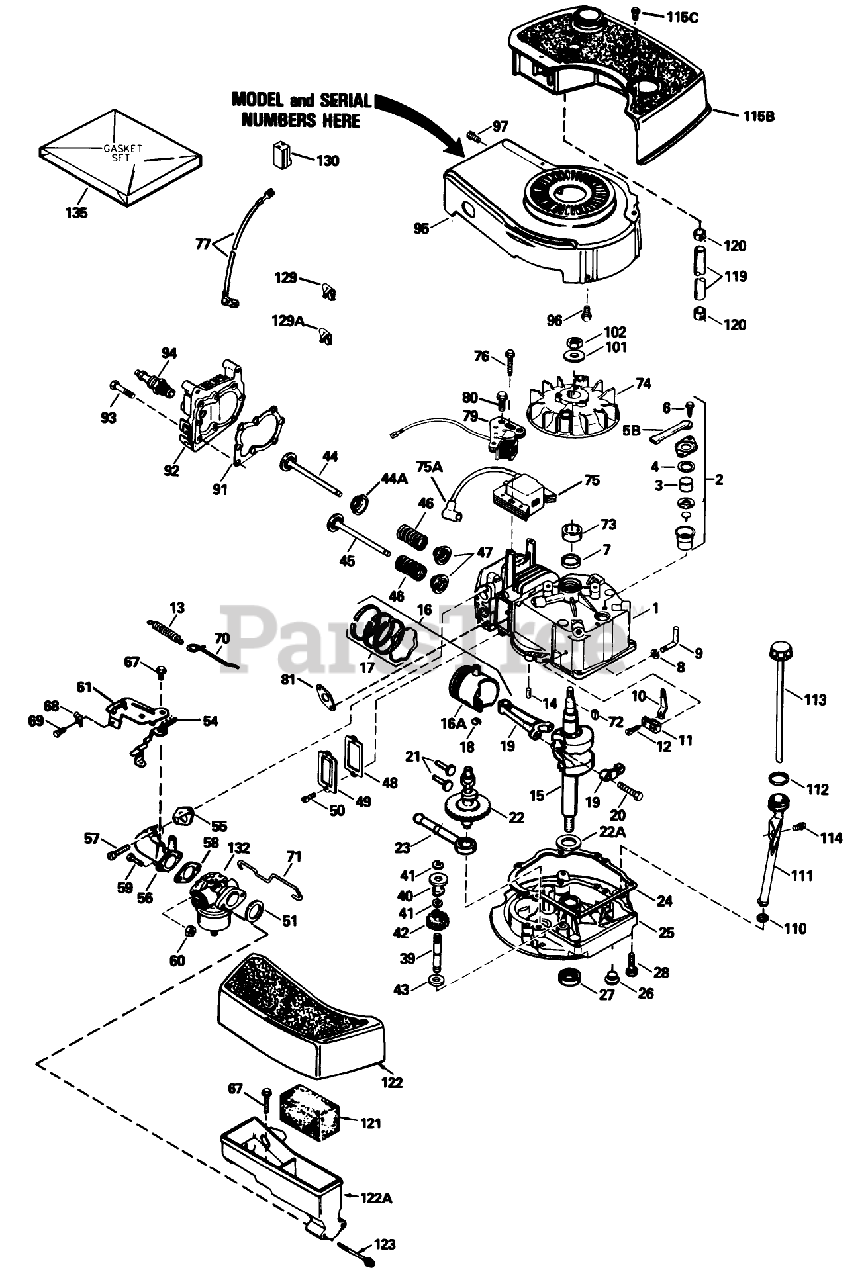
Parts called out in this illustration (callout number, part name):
1	Cylinder Assy. (Inc. #2 4)
2	Breather Assy. (Incl. Ref. #46 thru 51)
3	Element-Breather
4	Gasket-Breather
5B	Tube, Breaker
6	Screw (10-24 x 9/16)
7	Seal-Oil
8	Washer-Flat
9	Rod, Governor (Incl. No. 36)
10	Governor Lever
11	Clamp-Lever, Governor
12	Screw
13	Spring Governor
14	Pin-Dowel
15	Crankshaft
16	Piston-Pin Ring Assy. (Std.)(Incl. Ref. #16A, 17 18)
16	Piston-Pin Ring Assembly (.010 oversize)(Incl. Ref. #16A, 17 18)
16	Piston, Pin Ring Assy. (.020 Oversize)(Incl. Ref. #13A, 14, 15)
16A	Piston Pin Assy. (Std.)(Incl. Ref. #14)
16A	Piston Pin Assembly (.010 oversize)(Incl. Ref. #18)
16A	Piston Pin Assy. (.020 Oversize) (Incl. Ref. #14)
17	Ring Set-Piston (Std.)
17	Ring Set, Piston(.0100versize)
17	Ring Set (.020" OS)
18	Ring-Retaining, Piston Pin
19	Rod Assy., Connecting (Incl. Ref. #17)
20	Bolt-Rod, Connecting
21	Lifter-Valve
22	Camshaft(Mech.Comp. Release)
22A	Washer-Thrust
23	Oil Pump ASM
24	Gasket
25	Flange-Mounting (Incl. Ref. #26, 27 39)
26	Plug Oil Drain
27	Seal-Oil
28	Screw (1/4-20 x 1-1/4)
39	Shaft-Governor
40	Spool-Governor
41	Ring-Retaining
42	Governor Gear ASM
43	Washer
44	Valve, Intake (Std.) (Incl. Ref. #40)
44	Valve, Intake (1/32" oversize)(Incl. No. 40)
44A	Seal Assy., Intake
45	Valve, Exhaust (Std.)(Incl. No. 40)
45	Valve, Intake (1/32" oversize)(Incl. No. 40)
46	Spring-Valve
47	Cap-Valve, Spring
48	Gasket-Cover, Valve
49	Cover-Valve
50	Screw
51	Gasket-Air Cleaner
54	Lever Control
55	Gasket-Intake Pipe
56	Pipe, Intake (Incl. No. 68)
57	Screw (1/4-20 x 1)
58	Gasket-Carburetor
60	Nut and Lock Washer (1/4-28)
61	Control Assy., Speed (Incl. Nos, 76, 78 89)
67	Screw, Hex Washer Hd Shoulder Self-Tap
68	Conduit
69	Screw (10-32 x 3/8)
70	Link Governor Spring
71	Link-Throttle
72	Key-Flywheel
73	Spacer
74	Flywheel
75	Solid State
75A	Cover-Spark Plug
76	Screw
77	Wire-Ground
79	Coil, Alternator
80	Screw (8-32x27/64)
81	Gasket, Exhaust
91	Gasket-Cylinder Head
92	Head-Cylinder
93	Screw (5/16-18x1-1/2)
94	Spark Plug-Resistor (R J19 L M)
95	Housing-Blower
96	Screw (1/4-20x19/32)
97	Screw (10-24 x 9/16)
101	Washer-Belleville
102	Nut-Flywheel
110	Gasket
111	Tube, Oil Fill
112	O-Ring
113	Dipstick, Oil
114	Screw (10-32 x 1/2)
115B	Tank-Fuel
115C	Screw (10-32 x 35/64)
119	Line-Fuel
120	Clamp-Line, Fuel
121	Filer, Air
122	Cove, Air Cleaner
122A	Body Air Cleaner
123	Screw Fil Hd.
129	Clip-Wire
129A	Clip, Breather
130	Connector-Body
132	Carburetor (Incl. Ref. #71)
135	Gasket Set
